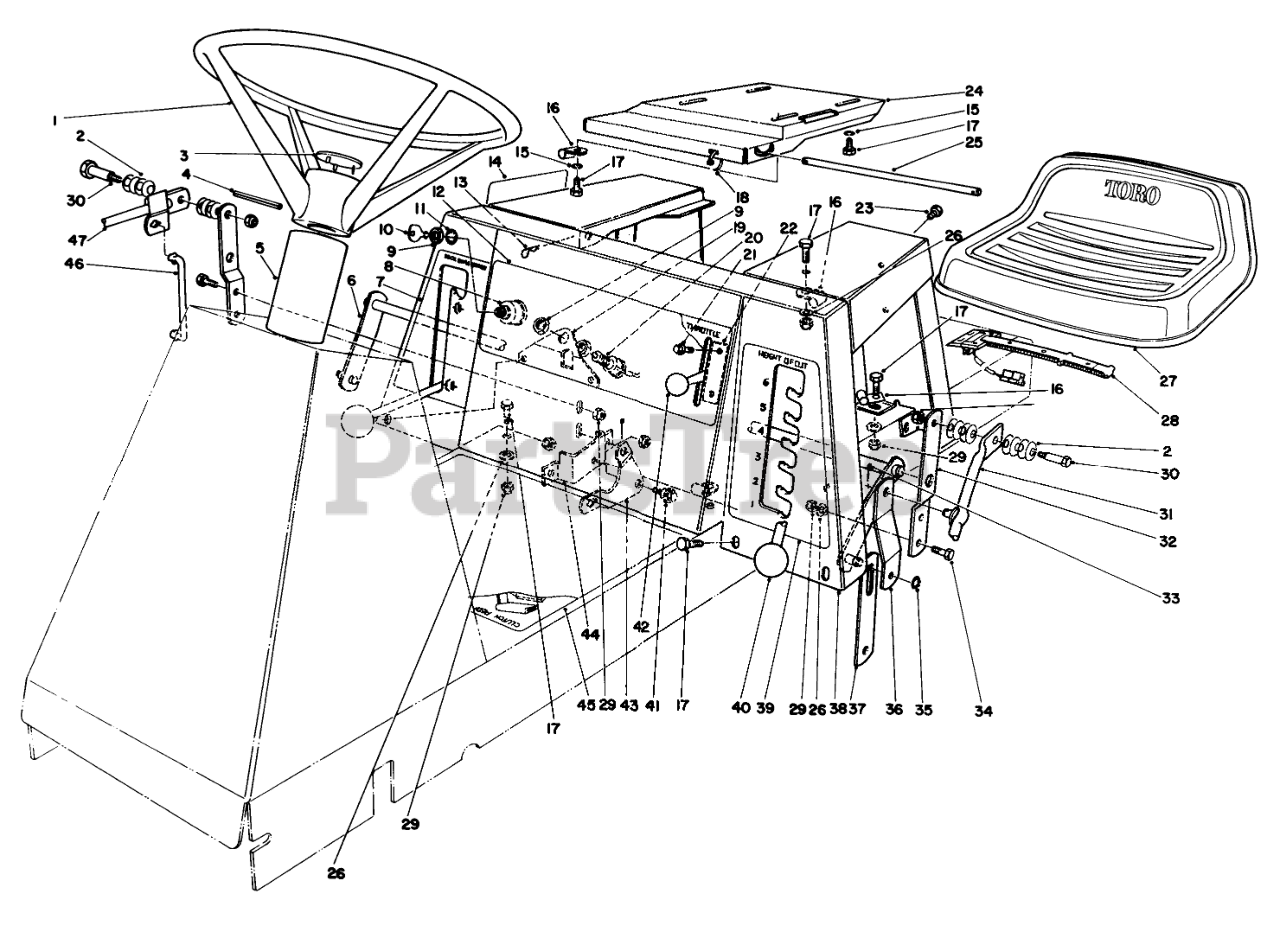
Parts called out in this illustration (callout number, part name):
1	Steering Wheel Assembly (Incl. Ref. #3)
2	WASHER-BELLEVILLE
3	Cap-Steering Wheel
4	PIN-ROLL
5	STRG. SHAFT COVER
6	Arm
7	DECK ENGAGE DECAL
8	Switch-lgnition (Incl. Ref. #9-11)
9	NUT-HH
10	Key
11	WASHER-TOOTH, INTERNAL
12	IGN & THROTTLE DECAL
13	PIN-COTTER
14	Decal Shift Pattern
15	Lockwasher
16	CLAMP
17	SCREW-HH
18	TIE-CABLE
19	SWITCH MT BRKT
20	DECK SWITCH
21	SCREW-HWHTF
22	Control-Throttle (Incl. Ref. #42)
23	SCREW-HH
24	SEAT BASE RO
25	SEAT BASE ROD
26	WASHER-PLAIN
27	Seat
28	SWITCH-SEAT
29	NUT-LOCK, NI
30	BOLT-SHOULDER
31	HOC LEVER WA B
32	Bracket
33	Cotter Pin
34	SCREW-HH
35	RING-RETAINING
36	HOC ENGAGE BRKT R
37	DECK SUSP LINK B
38	Body-Seat
39	HOC DECAL
41	SCREW-SHOULDER
42	Knob
43	DECK ENGAGE BELLCRANK
44	BELLCRANK MTG BRKT
45	INSTRUCTION DECAL
46	BELLCRANK LINK(PLTD)
47	Lift Arm Assembly
